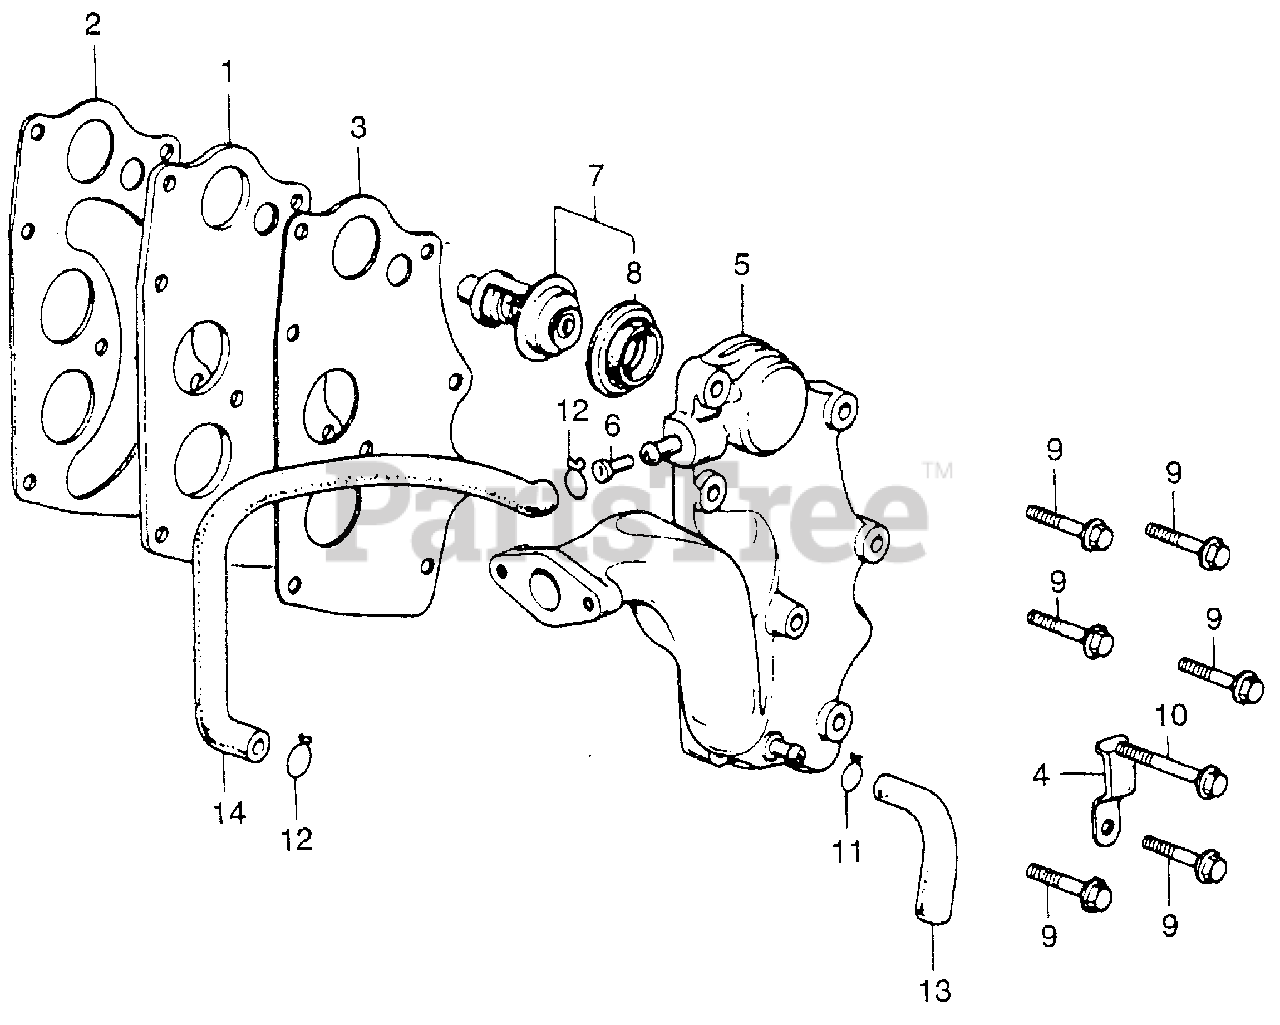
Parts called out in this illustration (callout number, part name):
1	PLATE, EX. CHAMBER
2	GASKET, EX. CHAMBER
3	GASKET, EX. CHAMBER
4	CLAMP, FUEL TUBE (NOT AVAILABLE)
4	CLIP, WIRE
5	MANIFOLD, IN. *NH8* (DARK GRAY)
6	NOZZLE, THROTTLE (NOT AVAILABLE)
7	THERMOSTAT ASSY.
8	RUBBER, THERMOSTAT
9	BOLT, FLANGE (6X28)
10	BOLT, FLANGE (6X40)
11	CLIP, TUBE (B8)
12	CLIP, TUBE (B12)
13	TUBE, WATER CHECK (NOT AVAILABLE)
14	TUBE, BYPASS
